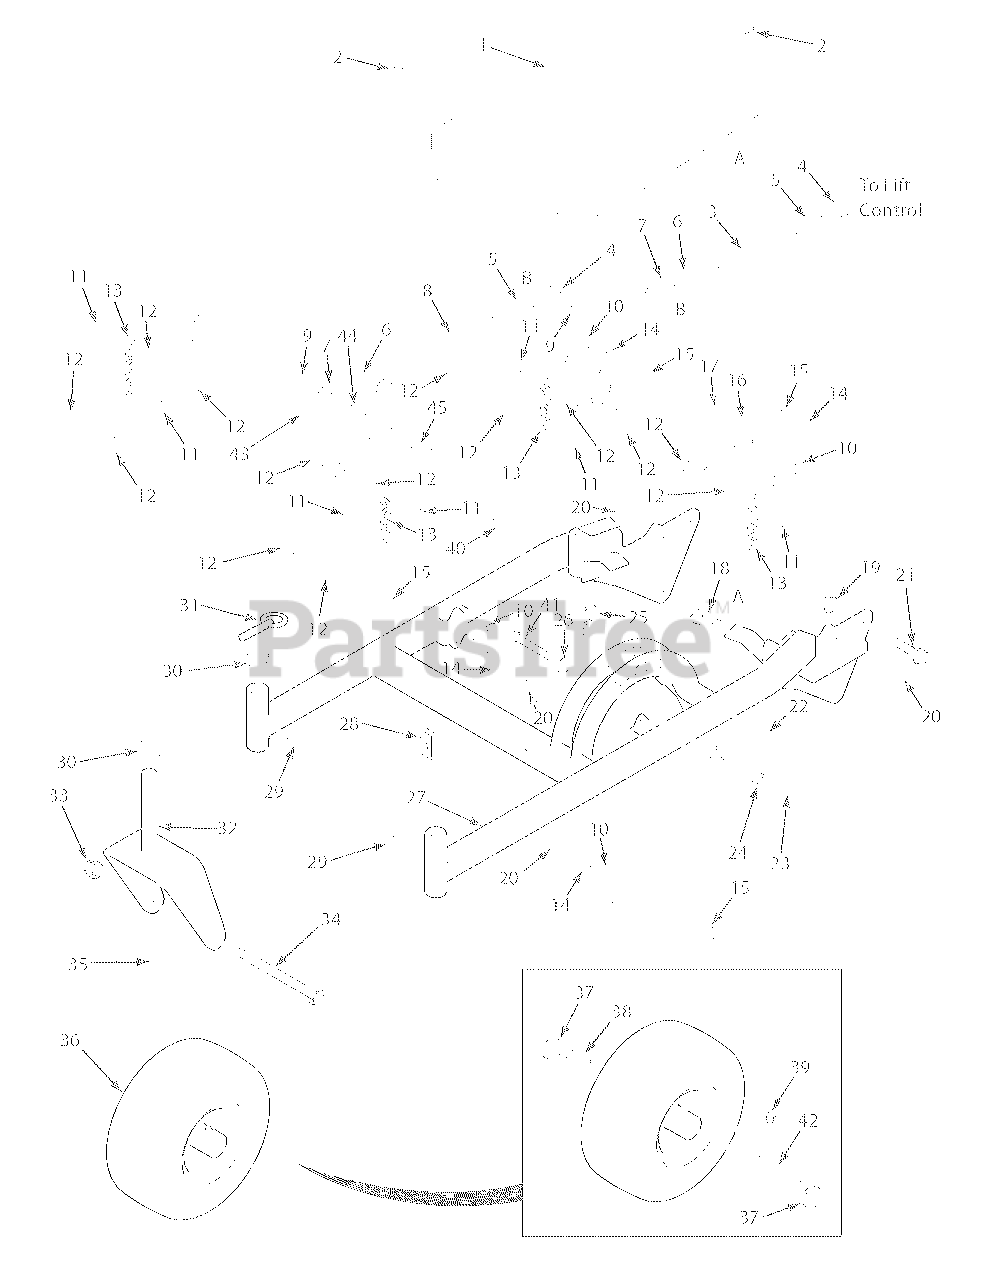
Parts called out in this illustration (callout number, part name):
1	Belt Cover, 36A
2	Knob w/Stud
3	Linkage Assembly, Deck Lift
4	Rod End, 1/2-20 LH
5	Nut, 1/2-20 UNF LH Jam
6	Nut, 1/2-20 RH
7	Rod End, 1/2-20 RH
8	Linkage Assembly, Deck Lift
9	Nut, Elastic Stop 1/2-13
10	Bearing
11	Bolt, Hex Head 3/8-16 x 1-1/2"
12	N ut, Serrated Flange 3/8-16
13	Chain
14	Flatwasher, 5/16-.375 x .875 x .083
15	Nut, Elastic Stop 5/16-18
16	Rear Deck Lift Weldment
17	Bolt, Hex Head 1/2-13 x 2-1/2"
18	U-Nut, 3/8-16
19	Nut, Spiral Lock 1/2-13
20	Bolt, Hex Head 5/16-18 x 1-1/4"
21	Capscrew, Serrated Flange 1/2-13 x 1"
22	Ring Pin Assembly
23	Lanyard
24	Nut, Elastic Stop 3/8-16
25	Hair Pin Cotter, .177 x 3-1/4"
26	Flatwasher, 3/8-.391 x .938 x .105
27	Frame Weldment
28	U-Nut, 3/8-16
29	Grease Fitting
30	Bushing, 1.003 I.D.
31	Quick Pin
32	Caster Wheel Yoke
33	Nut, Elastic Stop 1/2-13
34	Bolt, Hex Head 1/2-13 x 6-1/2"
35	Sleeve, Caster Wheel
36	Caster Wheel Assembly
37	Bearing, Oilite
38	Roller Bearing
39	Grease Fitting
40	Spacer
41	Bolt, Hex Head 3/8-16 x 2-3/4"
42	Roller Bearing
43	Front Deck Lift Weldment
44	Spacer
45	Bolt, Hex Head 1/2-13 x 2-3/4’
